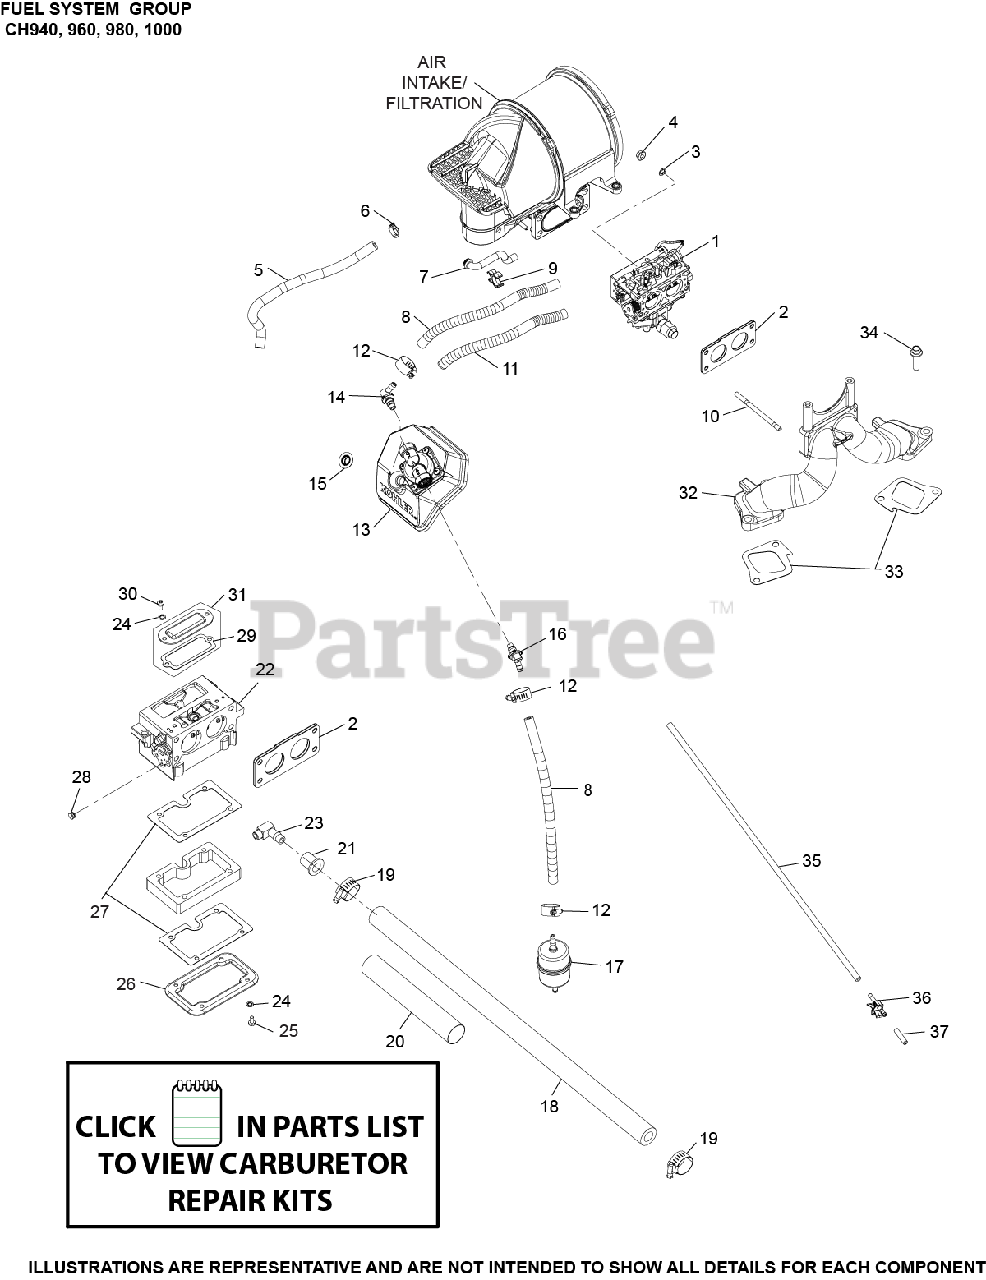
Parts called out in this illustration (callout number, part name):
1	KIT, CARBURETOR W/GASKETS USE 62 853 45-S
2	GASKET, CARBURETOR
3	WASHER, INT TOOTH LOCK 1/4"
4	NUT, FLG M6X1.0
7	HOSE, CARBURETOR VENT
8	HOSE,LW PERM.FUEL 24.00"-USE 25 111 81-S
9	RETAINER, CLIP
10	STUD
11	SLEEVE, ANTI ABRASION -USE 25 431 12-S
12	CLAMP, HOSE (KM)-USE 25 237 31-S
13	KIT, FUEL PUMP
14	KIT, 90 DEG. FITTING
16	KIT, 45 DEG. FITTING
17	FILTER, FUEL
32	KIT, INTAKE MANIFOLD
33	GASKET, INTAKE MANIFOLD
34	SCREW, FLG M8X1.25X30
35	HOSE, EVAPORATIVE 20"
36	CONNECTOR, EVAPORATIVE
37	CAP, MASKING
